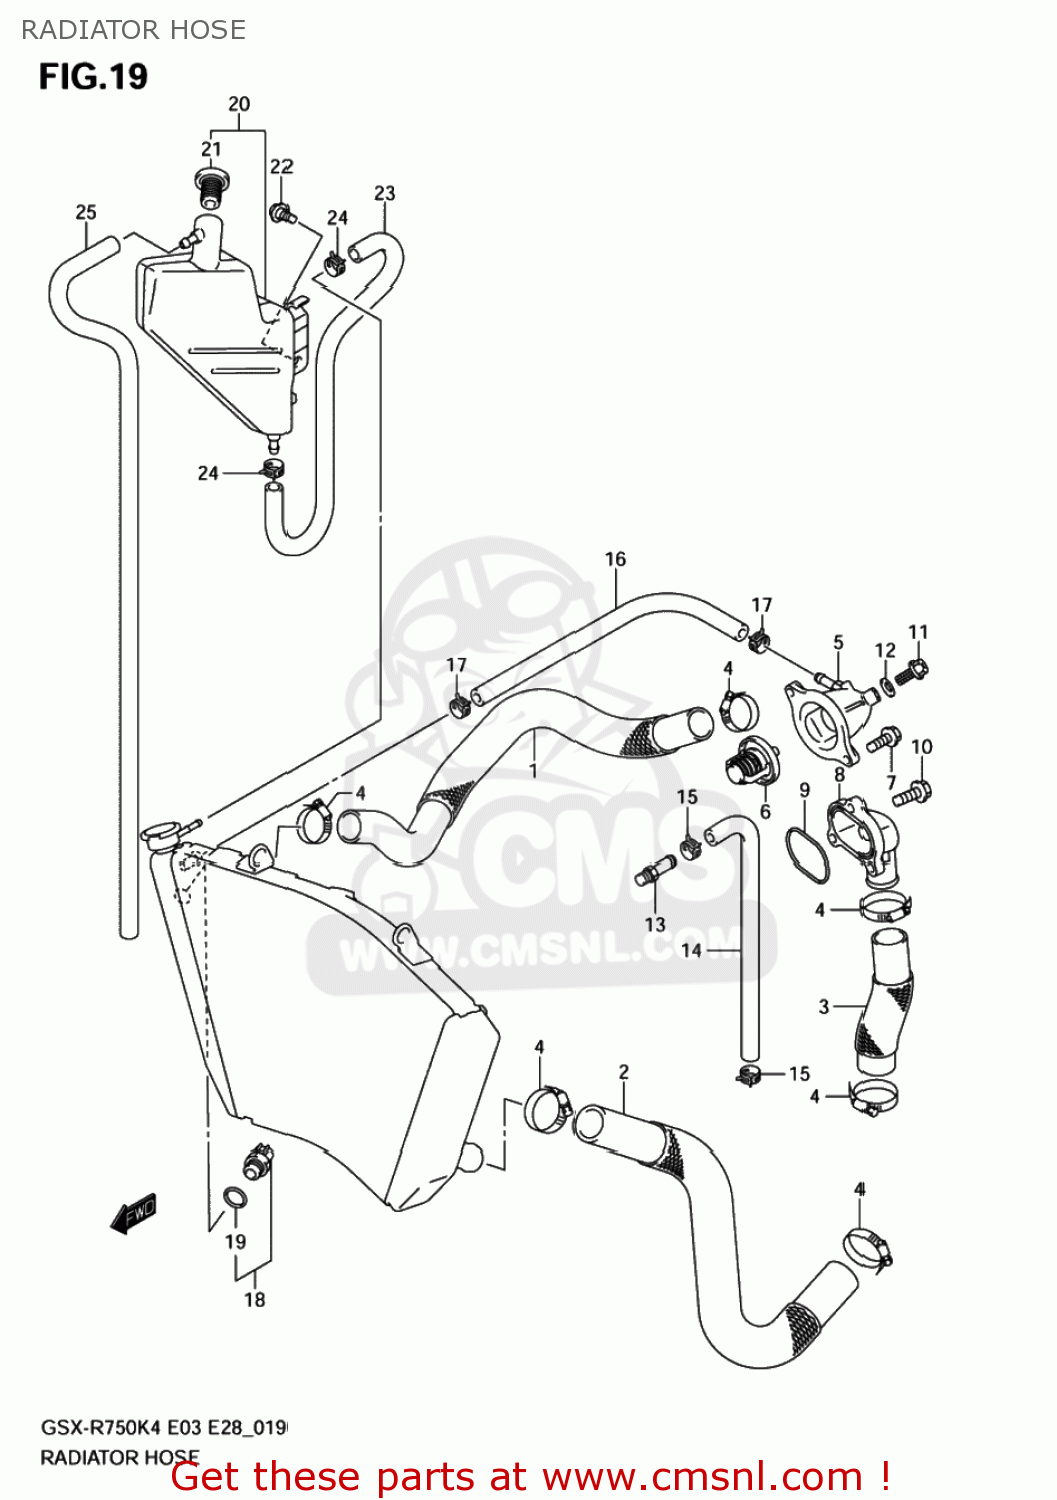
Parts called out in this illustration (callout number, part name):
1	HOSE,RADIATOR INLET
2	HOSE,RADIATOR OUTLET
3	HOSE,CYLINDER INLET
4	CLAMP
5	COVER,THERMOSTAT
6	THERMOSTAT COM
7	SCREW
8	CONNECTOR,CYL.
9	O RING,CYL WATER CONNECTOR
10	SCREW
11	UNION BOLT,AIR VENT
12	GASKET(6.4X11.5X0.8) (NAS)
13	BOLT UNION
14	HOSE,WATER BYPASS
15	CLAMP
16	HOSE(5X11X600)
17	CLIP
18	SWITCH,RADIATOR FAN
19	O-RING
20	TANK ASSY,RESERVOIR
21	CAP,RESERVOIR TANK
22	BOLT(6X12)
23	HOSE,RESERVOIR TANK INLET
24	CLIP
25	HOSE,RESERVOIR
